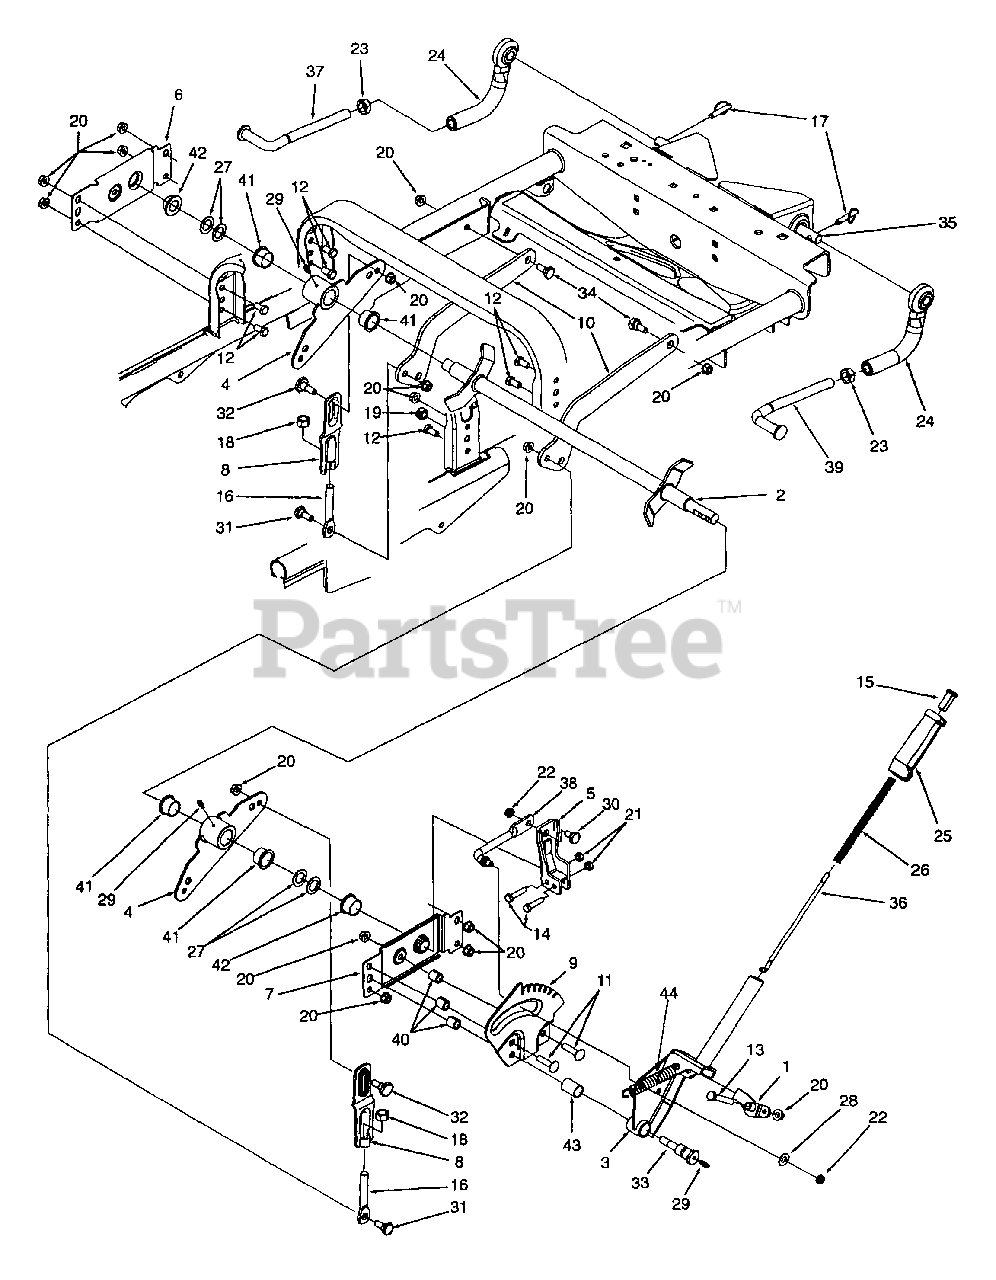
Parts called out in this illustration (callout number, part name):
7	Bracket, Shaft Mtg. RH
11	Bolt, Carriage, 3/8-16 x 1.5
12	Screw, Hex Cap, 3/8-16 x .75 GR5
13	Screw, Hex Cap, 3/8-16 x 2-1/4
14	Screw, Hex Cap, 5/16-18 x 1.38 GR5
15	Button, Handle
16	Link, Eye Bolt Adjustment
17	Clevis Pin, w/ Detent Ball
18	Nut, Hex, 1/2-13
19	Nut, Hex Center Lock, 7/16-14
20	Nut, Hex Flange Lock, 3/8-16
21	Nut, Hex Center Lock, 5/16-18
22	Nut, Hex Insert Lock Jam 3/8-16
23	Nut, Hex Jam, 5/8-18
24	Link, Parallel
25	Grip, Deck Lift Handle
26	Spring, Compression
27	Washer, Flat, .79 x 1.24 x .06
28	Washer, Flat, .406 x .875 x .06
29	Fitting, Grease
30	Bolt, Shoulder
31	Bolt, Shoulder
32	Bolt, Shoulder
33	Bolt, Lift Handle Shoulder
34	Bolt, Shoulder
35	Rod, Parallel Link Front Mtg.
36	Rod, Lift Handle
37	Rod, Connecting LH
38	Rod, Lift Link
39	Rod, Connecting RH
40	Spacer, .448 x .688 x .673
41	Bearing, Flange, 1.0 ID
42	Bearing, Flange, .75 ID x 1.0 OD
43	Bearing, Sleeve, .75 x .875 x 1.25
44	Spring
